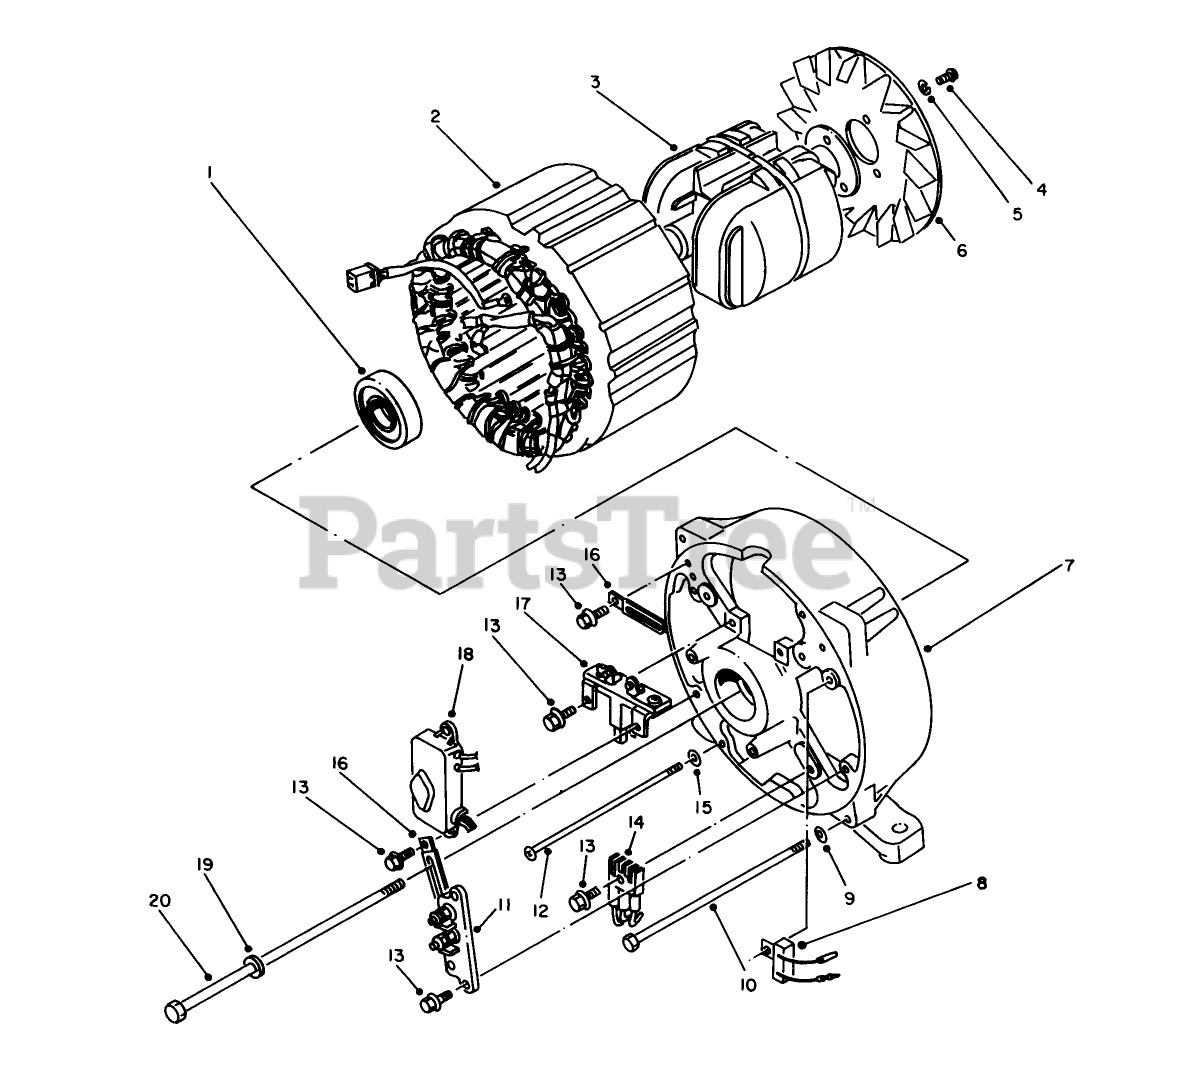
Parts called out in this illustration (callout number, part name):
1	Bearing
2	Stator
3	Rotor
4	SCREW
5	Washer
7	Bracket-Rear
8	Register
9	Washer
10	BOLT (6X171)
11	Terminal
12	Screw
14	Diode
15	WASHER
16	Clamp
17	Holder-Brush
18	Regulator-Voltage
19	Washer
